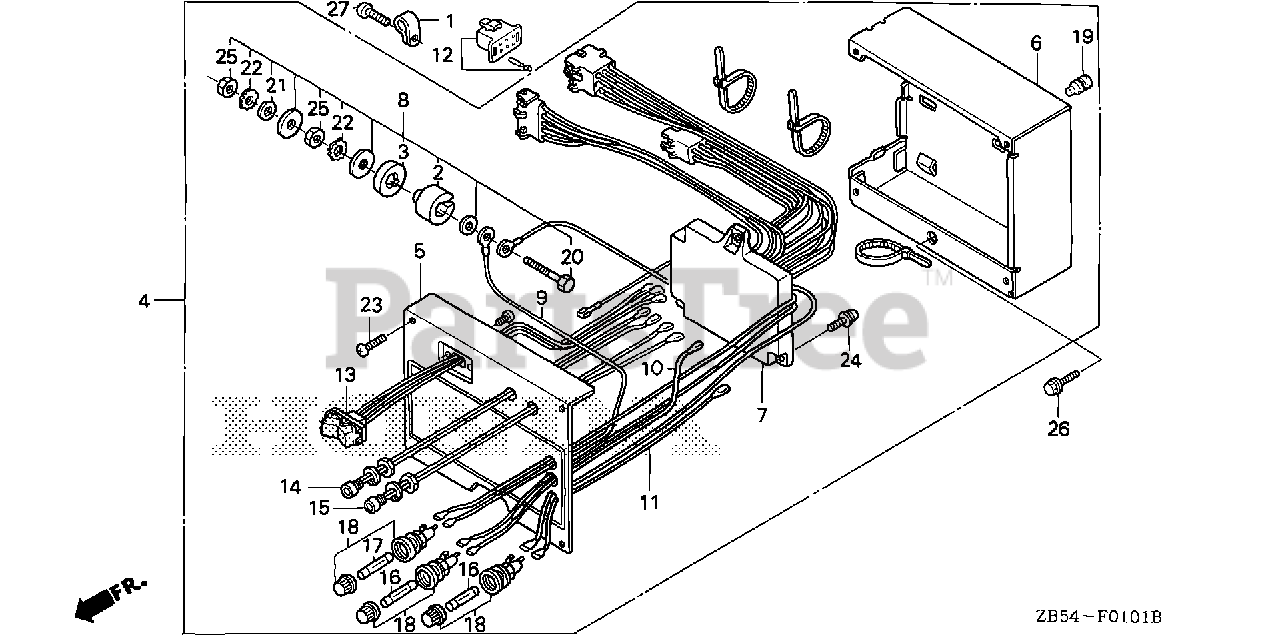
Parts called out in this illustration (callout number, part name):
1	CLAMP F, CABLE
2	COLLAR A, D.C. TERMINAL
3	COLLAR B, D.C. TERMINAL
4	BOX ASSY., CONTROL *NH192M* (GENTLY SILVER METALLIC)
5	PANEL, CONTROL *NH192M* (GENTLY SILVER METALLIC)
6	BOX, CONTROL
7	CONTROL ASSY.
8	TERMINAL SET, BATTERY
9	WIRE A, FUSE HOLDER
10	WIRE B, FUSE HOLDER
11	WIRE C, FUSE HOLDER
13	SWITCH, ENGINE
14	SOCKET ASSY., LAMP (GREEN)
15	SOCKET ASSY., LAMP (RED)
17	FUSE (15A)
18	HOLDER, FUSE
19	CUSHION, RR. FENDER
20	BOLT, D.C. TERMINAL
21	WASHER, D.C. TERMINAL
22	WASHER, STAR
23	SCREW, PAN (4X12)
24	SCREW-WASHER (4X12)
25	NUT, HEX. (8MM)
26	BOLT, FLANGE (6X12)
27	SCREW-WASHER (5X12)
